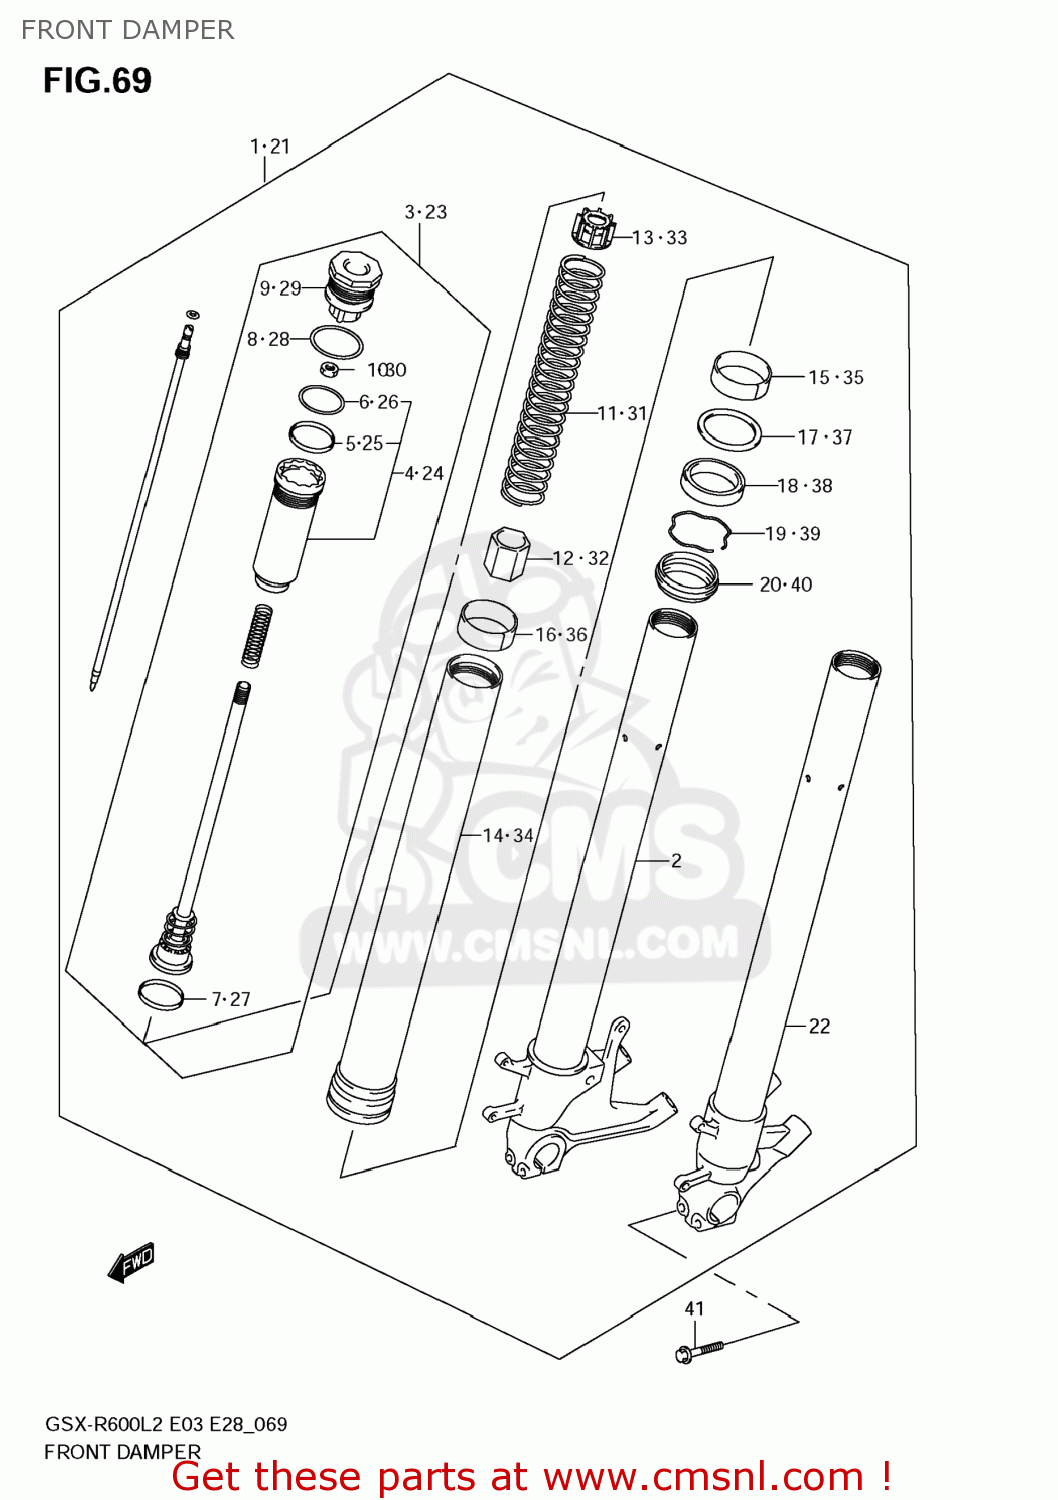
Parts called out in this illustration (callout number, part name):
1	DAMPER ASSY,FR FORK,R
2	TUBE,INNER,R
3	ROD,PISTON
4	CASE,ROD GUIDE
5	PISTON RING
6	O RING
7	RING,PISTON
8	O RING,FORK BOLT
9	BOLT
10	NUT
11	SPRING
12	COLLAR,SPRING
13	COLLAR,SPRING
14	TUBE,OUTER
15	BUSH,GUIDE
16	BUSH,SLIDE
17	SPACER,SEAL
18	SEAL,OIL
19	CIRCLIP,FORK OIL SEAL
20	SEAL,DUST
21	DAMPER ASSY,FR FORK,L
22	TUBE,INNER,L
23	ROD,PISTON
24	CASE,ROD GUIDE
25	PISTON RING
26	O RING
27	RING,PISTON
28	O RING,FORK BOLT
29	BOLT
30	NUT
31	SPRING
32	COLLAR,SPRING
33	COLLAR,SPRING
34	TUBE,OUTER
35	BUSH,GUIDE
36	BUSH,SLIDE
37	SPACER,SEAL
38	SEAL,OIL
39	CIRCLIP,FORK OIL SEAL
40	SEAL,DUST
41	BOLT
